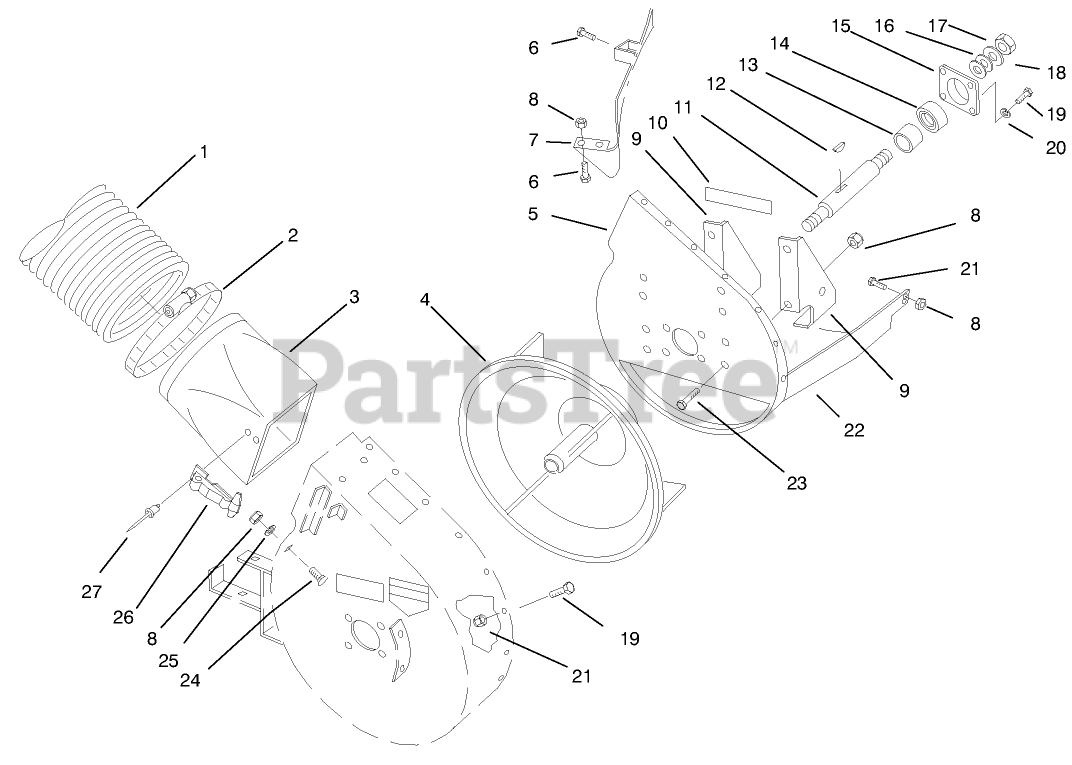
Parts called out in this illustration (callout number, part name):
1	Hose-Flexible (Ref.)
2	CLAMP
3	ADAPTER
4	IMPELLER - WELDED BLACK
5	Mount Plate Asm (Incl. Ref. #10)
6	SCREW
7	BAFFLE W.A. B
8	NUT-LOCK, NI
8	SPACER-BEARING
9	BRACKET-BLOWER MT B
10	DECAL
11	SHAFT- BLOWER
13	SPACER
14	BEARING-BALL
15	CUP-BEARING
16	WASHER-FLAT
17	NUT 5/8-11 L.H.
18	WASHER-FLAT
19	SCREW-HH
20	WASHER-LOCK
21	NUT-LOCK, NI
22	DEFLECTOR-BLOWER B
23	SCREW-HH
24	BOLT-CARR
25	WASHER-PLAIN
26	HANDLE ASM
27	RIVET-POP
